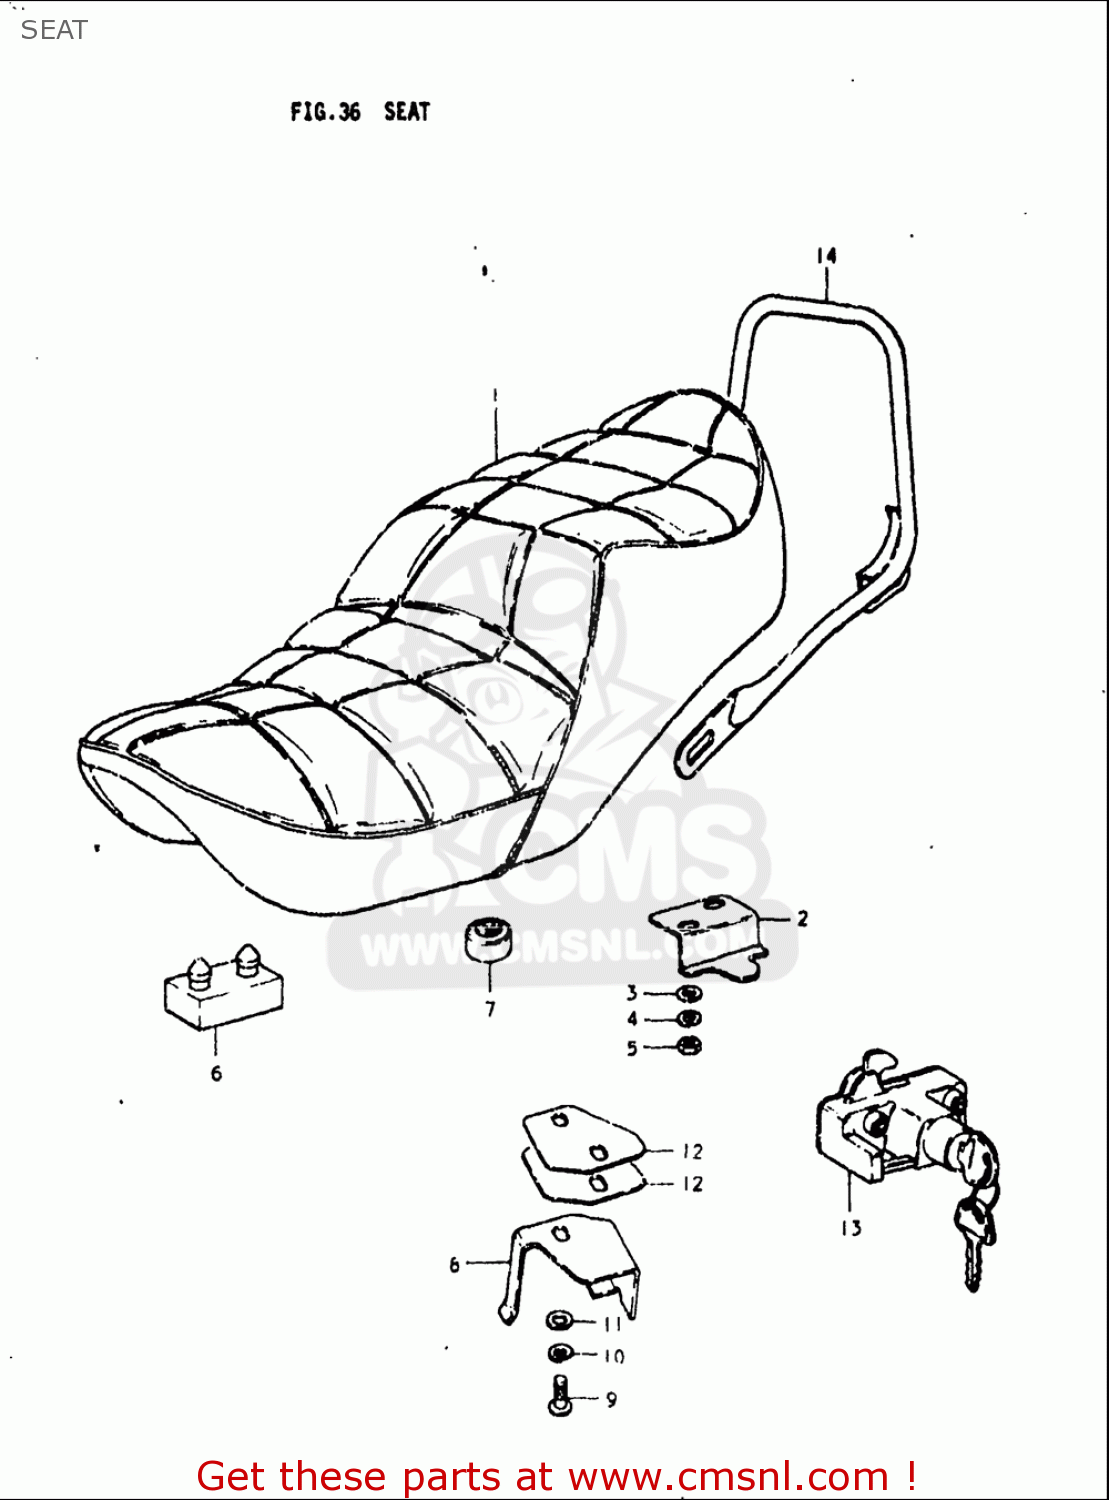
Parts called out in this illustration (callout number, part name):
3	WASHER
4	WASHER,LOCK
6	CUSHION
7	CUSHION
9	BOLT
10	WASHER,LOCK
11	WASHER
